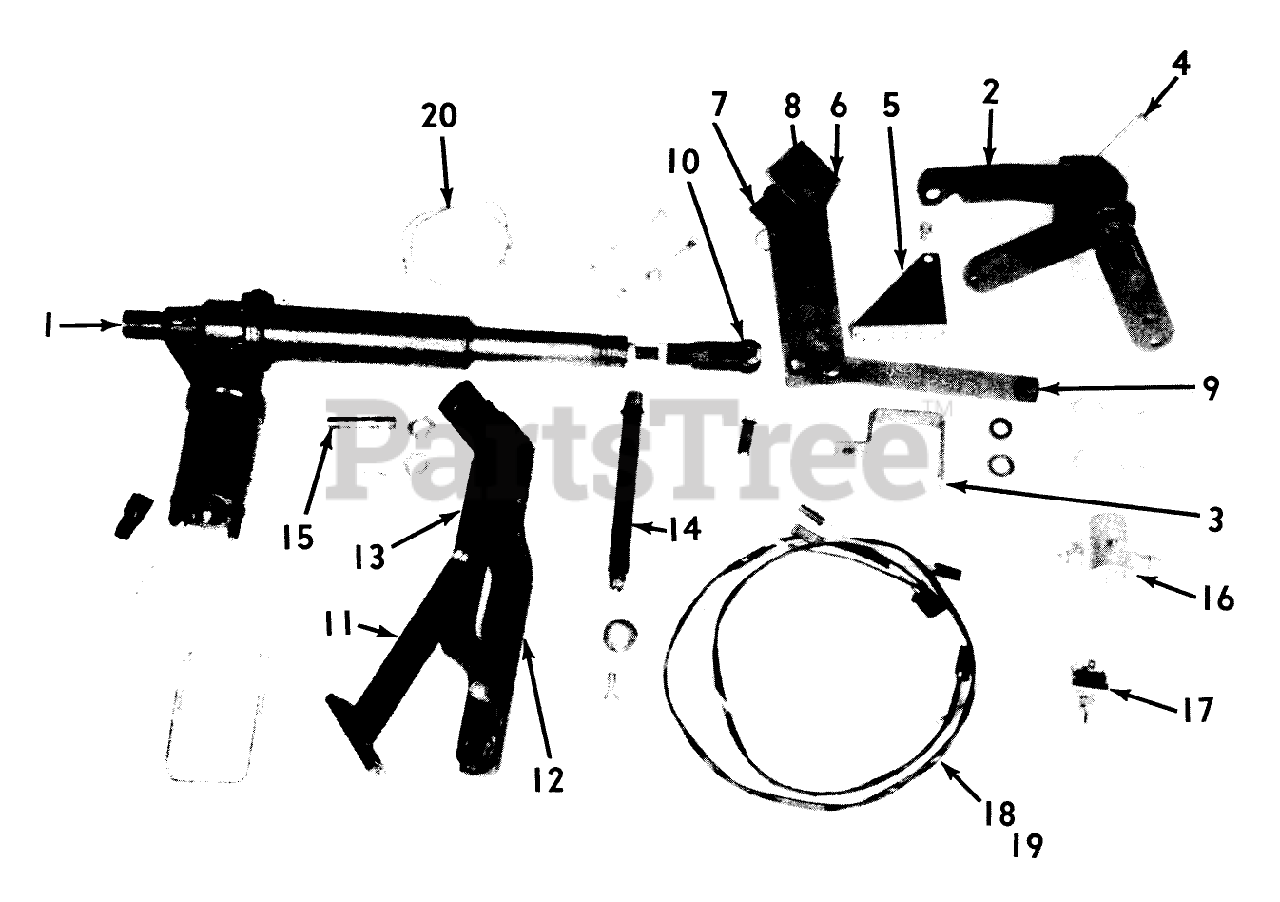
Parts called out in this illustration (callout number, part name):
1	Assembly-Linear Actuator
2	Lift Arm
3	Bracket
4	Arm
5	Indicator Plate
6	Bracket-Pivot Mounting
7	Assembly-Pivot Arm
8	Pin-Pivot
9	Assembly-Lift Link
10	Clevis
11	Assembly-Brace
12	Assembly-Frame Arm
13	Assembly-Frame Arm
14	Pin Anchor
15	Pin-Anchor-Rear
16	Solenoid
17	Switch
18	Harness-Wiring
19	Wire-Battery-to-Solenoid
20	Wire-Accessory-to-Solenoid
